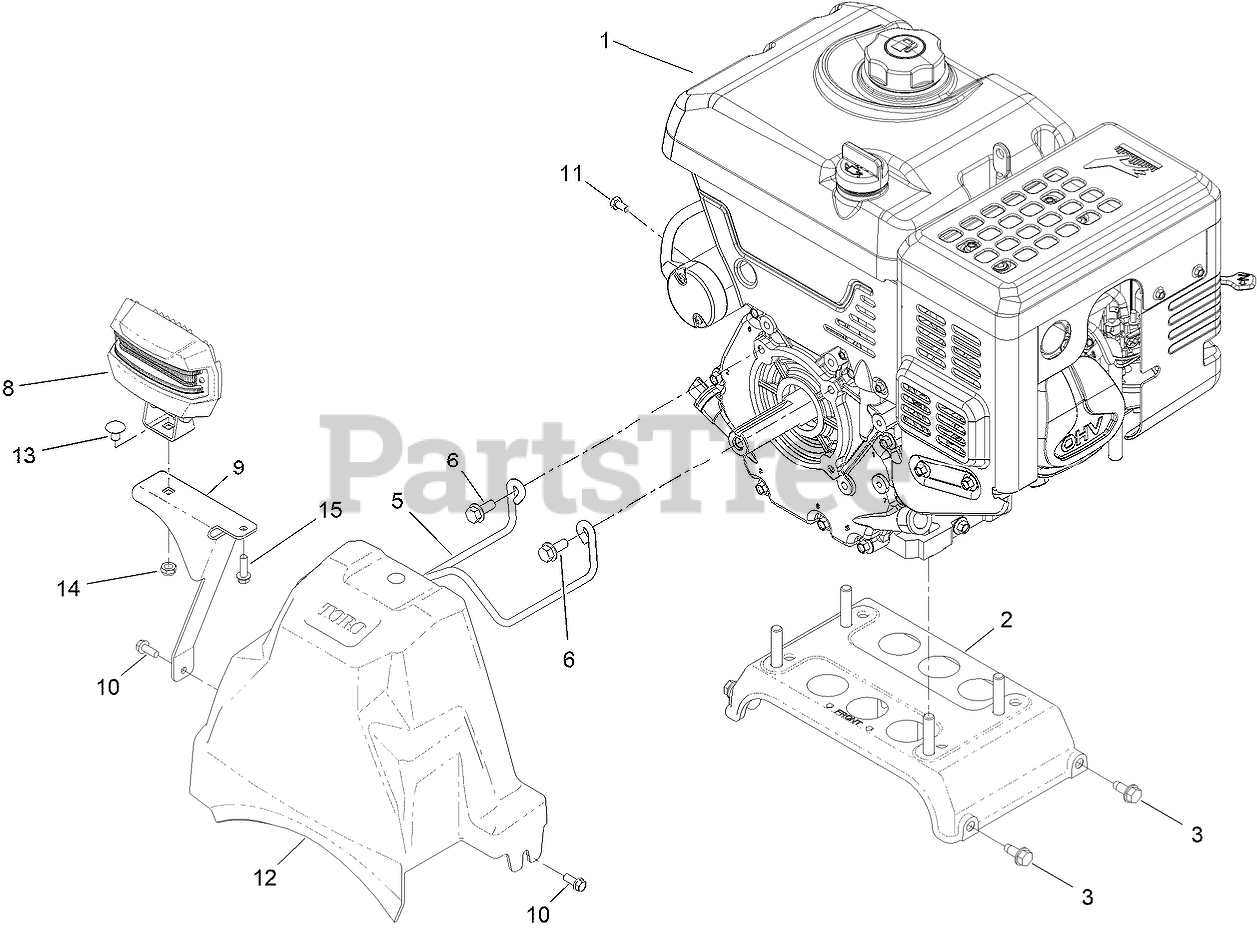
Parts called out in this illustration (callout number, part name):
1	ENGINE-LC190FDS-1
2	ENGINE PLATE ASM
3	SCREW-HWHTF
5	BELT GUIDE
6	SCREW-HH
8	LED LIGHT ASM
9	BRACKET-LIGHT
10	SCREW-HWH
11	SCREW-HH
12	COVER-BELT
13	BOLT-CARR
14	NUT-HEX
15	SCREW-PLASTITE, HWH
